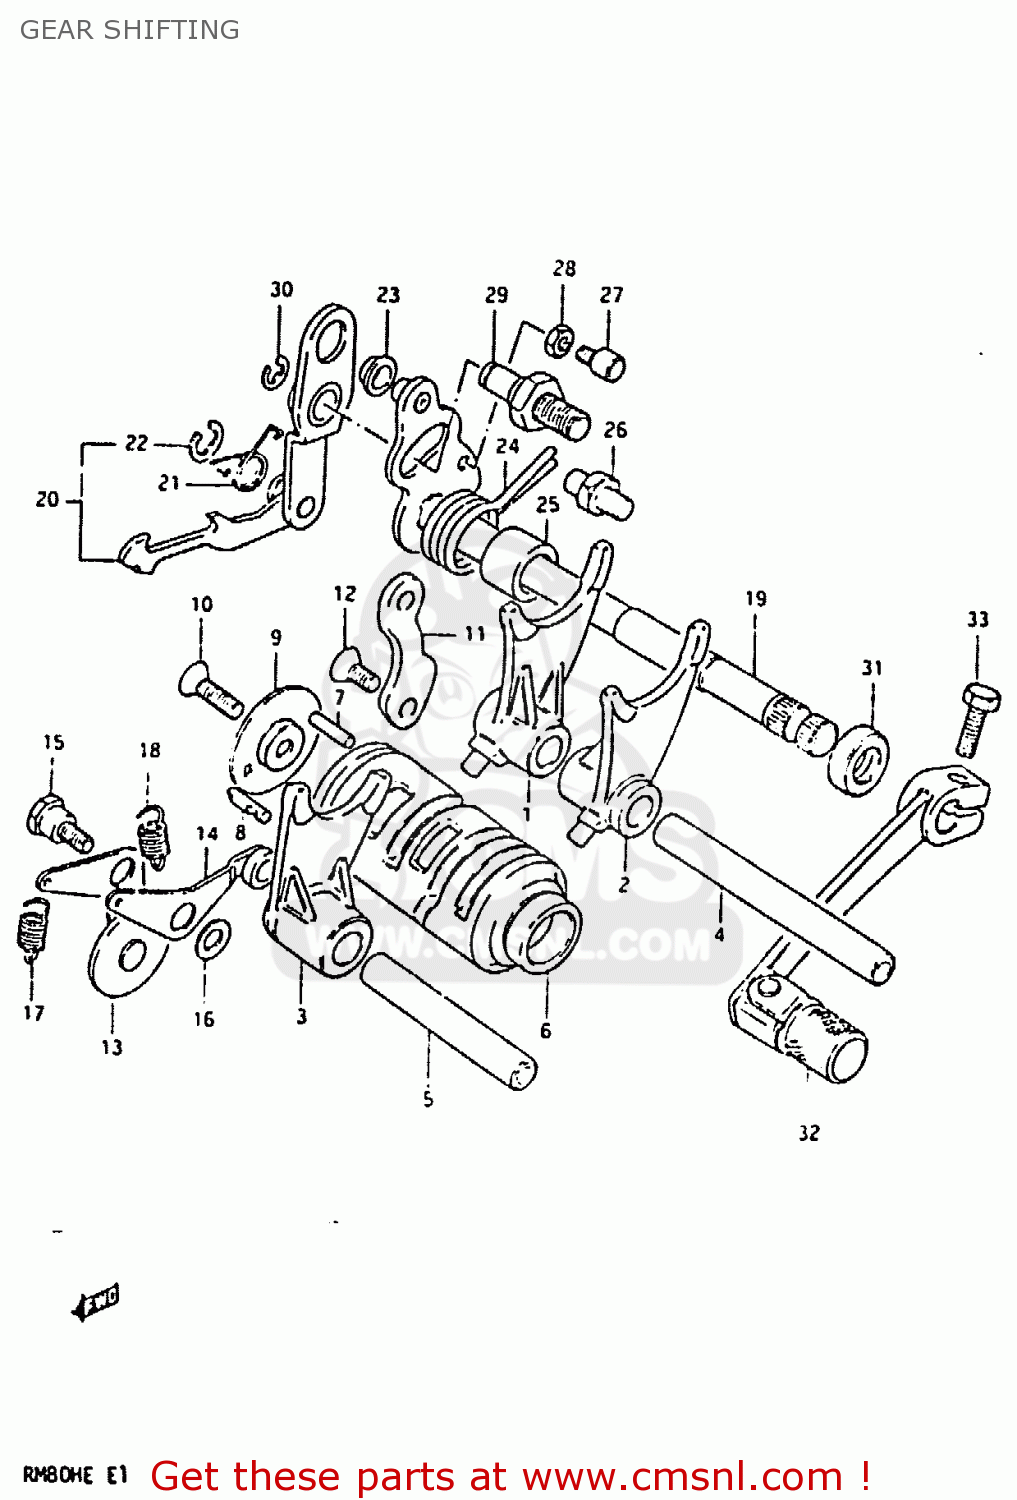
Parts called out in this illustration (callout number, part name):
1	FORK,GEAR SHIFT NO.1
2	FORK,GEAR SHIFT NO.2
3	FORK,GEAR SHIFT NO.2
4	SHAFT,GEAR SHIFT FORK
5	SHAFT,GEAR SHIFT FORK
6	CAM,GEAR SHIFT
7	PIN(4X15.8)
8	PIN
9	RETAINER,GEAR SHIFT CAM
10	SCREW
11	GUIDE,GEAR SHIFTING CABLE
12	SCREW
13	STOPPER,SHIFT CAM
14	STOPPER,GEAR SHIFT CAM
15	BOLT(6X18.3)
16	WASHER
17	SPRING
18	SPRING
19	SHAFT,GEAR SHIFT
20	PAWL,GEAR SHIFT
21	SPRING
22	E RING
23	SPACER(7X10X5)
24	SPRING
25	SPACER(12X20X15.3)
26	STOPPER,GEAR SHIFT CAM
27	BOLT,GEAR SHAFT RETURN SPR SET
28	NUT 6MM
29	STOPPER,GEAR SHIFT CAM
30	E RING 6MM
31	OIL SEAL
32	LEVER ASSEMBLY,GEAR SHIFTING
33	BOLT
